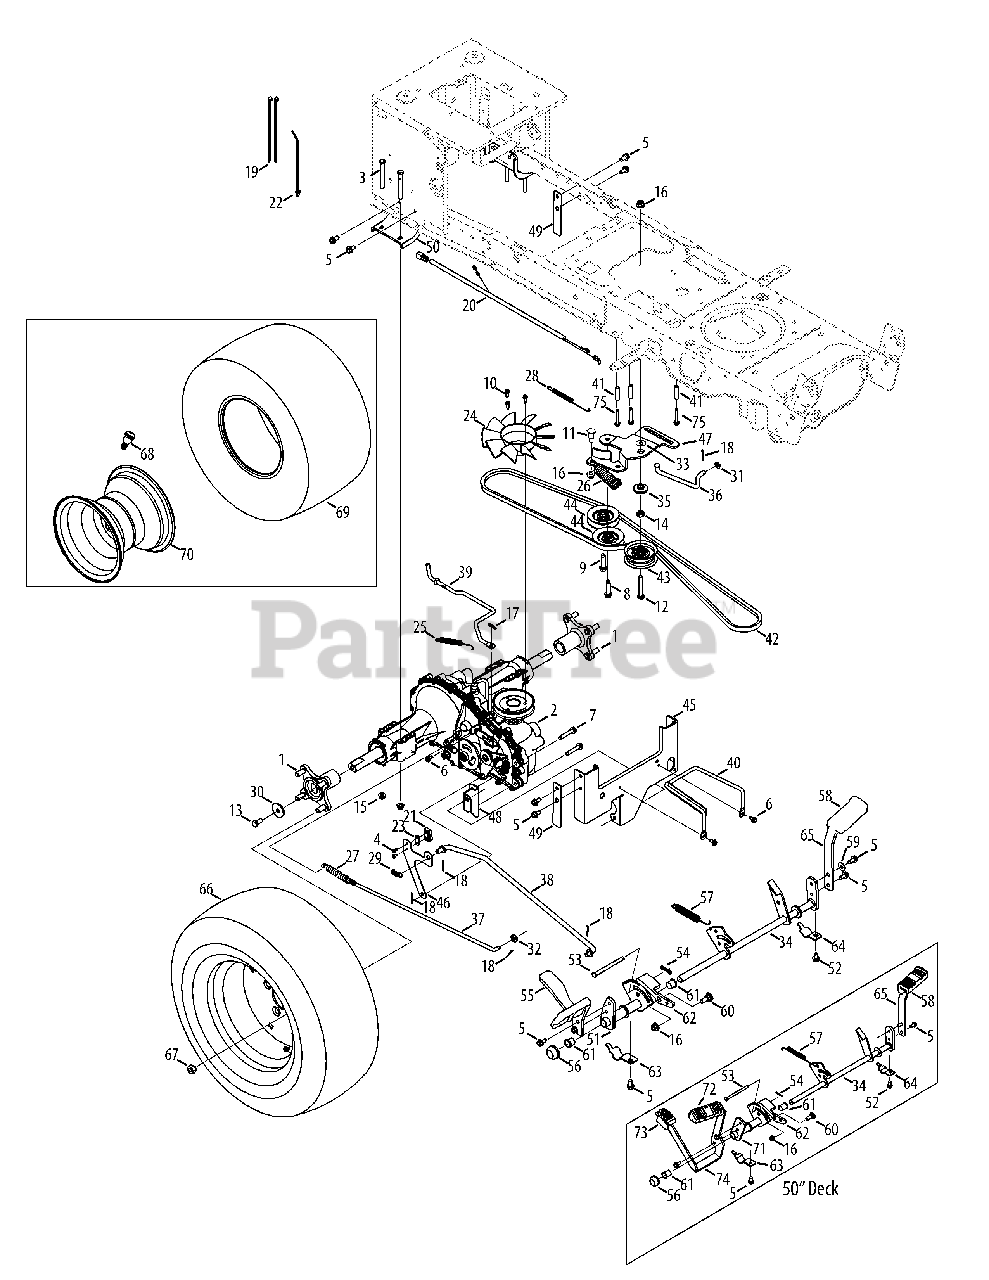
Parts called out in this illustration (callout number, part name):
1	Wheel Assembly Hub
2	Transmission Assembly
3	Hex Screw, 5/16-18x3.00
4	Screw, #8-18x0.500
5	Taptite Screw, 5/16-18x.750
6	Taptite Screw, 1/4-20x0.500
7	Taptite Screw, 5/16-18x1.750
8	Taptite Sems Screw, 3/8-16x1.500
9	Taptite Sems Screw, 3/8-16x1.875
10	Screw, #12-24x0.625
11	Screw, Shldr, .50 x .685 3/8-16
12	Hex Screw, 3/8-16x2.25
13	Hex Screw, 3/8-16x.750
14	Jam Nut, 7/16-20
15	Flangelock Nut, 5/16-18
16	Flangelock Nut, 3/8-16
17	Cotter Pin, .072 DIA. x 1.13 LG
18	Cotter Pin, 3/32x1.0
19	Cable Tie, 3/16 x .05 x 7.4
20	Jumper Harness
21	Short Spring Switch
22	Push Mount Cable Tie 7.5 LG
23	Insulator Nut Plate
24	Blade Fan
25	Extension Spring, .50 DIA x 5.0 LG
26	Extension Spring, 1.00 DIA x 4.75
27	Extension Spring, .59 OD x 4.00 LG
28	Extension Spring, .38 DIA x 5.6
29	Extension Spring, .375 OD x 1.44 LG
30	Flat Washer, .390 x 1.500 x .134
31	Flat Washer, .330 x .630 x .0635
32	Flat Washer, .344 x .750 x .120
33	Washer, Flat, .385 x 1.0 x .030
34	Brake Control Assembly
35	Shoulder Spacer, 1.375 x .380 x .183
36	Footpedal Bypass Transmission Rod
37	Brake Rod
38	Control Rod
39	Disengage Rod
40	Belt Keeper, 5/16
41	Spacer, 260 x .372 x 1.420 LG
42	V Belt, 4L x 77.0
43	Flat Idler Pulley, 2.75 OD
44	V Idler Pulley, 3.06
45	Torque Bracket
46	Switch Bracket
47	Center Idler Bracket
48	Deck Bracket
49	Plate Bracket
50	Axle Bracket
51	Hydro Pedal Bracket Assembly
52	Taptite Screw, 5/16-18x0.625
53	Clevis Pin, 5/16 x 3.985
54	Bow-Tie Cotter Pin
55	Control Pedal
56	Push Cap
57	Extension Spring, .63 DIA x 4.95 LG
58	Brake Pedal Pad
59	Bell Washer, .340 x .872 x .060
60	Shoulder Bolt, .500 x .270x3/8-16
61	Flange Bearing, .630 ID x .695 OD x .60
62	Cruise Latch
63	Pedal Support Bracket
64	Pedal Support Bracket, 5/8
65	Brake Pedal Bracket
66	Wheel Assembly
67	Lug Nut, 7/16-14
68	Air Valve
70	Rim Assembly
71	Hydro Pedal Bracket Assembly
72	Reverse Pedal Pad
73	Forward Pedal Pad
74	Drive Pedal Bracket
75	Taptite Screw, 1/4-20x1.750
